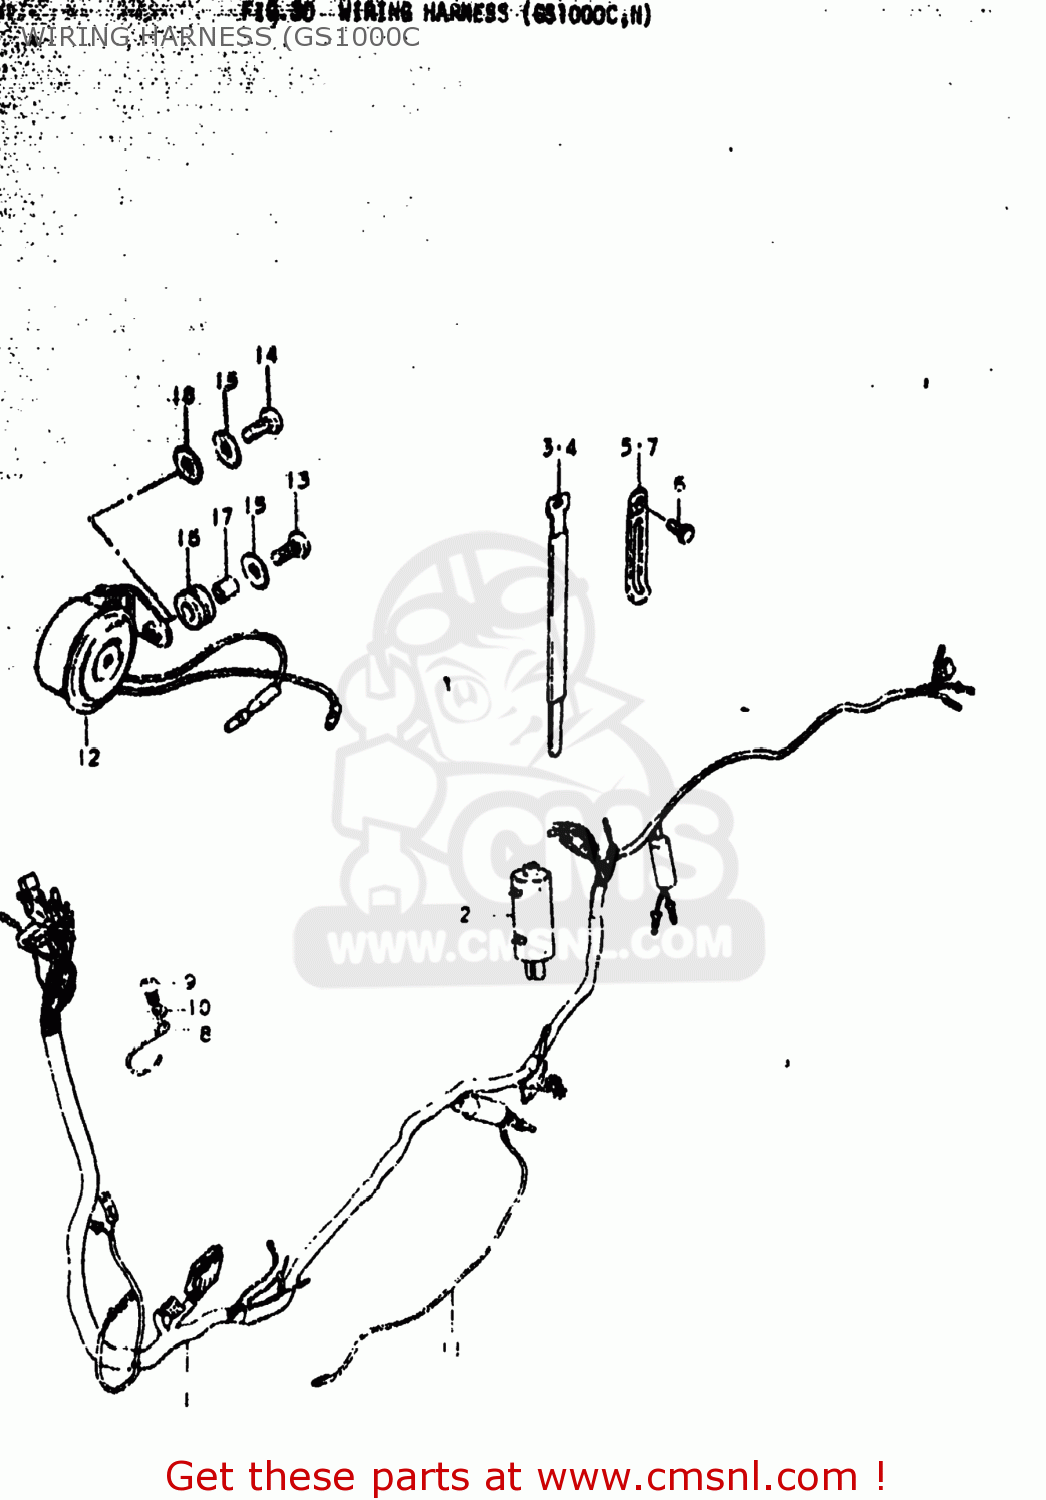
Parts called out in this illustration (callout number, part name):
1	HARNESS,WIRING
2	BOOT,WIRING HARNESS
3	CLAMP(L:120)
4	CLAMP
5	CLAMP
6	BOLT
7	CLAMP
8	GUIDE,WIRING HARNESS
9	SCREW 6X12
10	WASHER 6MM
11	WIRE
12	BUZZER ASSEMBLY,TURN SIGNAL
13	SCREW
14	SCREW
15	WASHER
16	CUSHION
17	SPACER (6.1X8X9.5)
18	WASHER(6X13X2)
